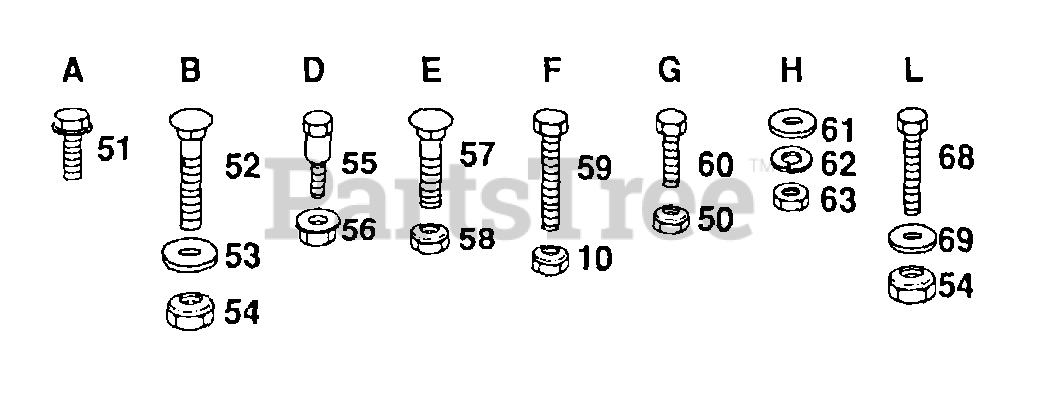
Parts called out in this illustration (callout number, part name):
51	SCREW LT
52	BOLT
53	WASHER
55	SHOULDER BOLT T
56	NUT T
57	BOLT
58	LOCKNUT
59	BOLT
60	BOLT
61	WASHER PM
68	BOLT
69	WASHER M
